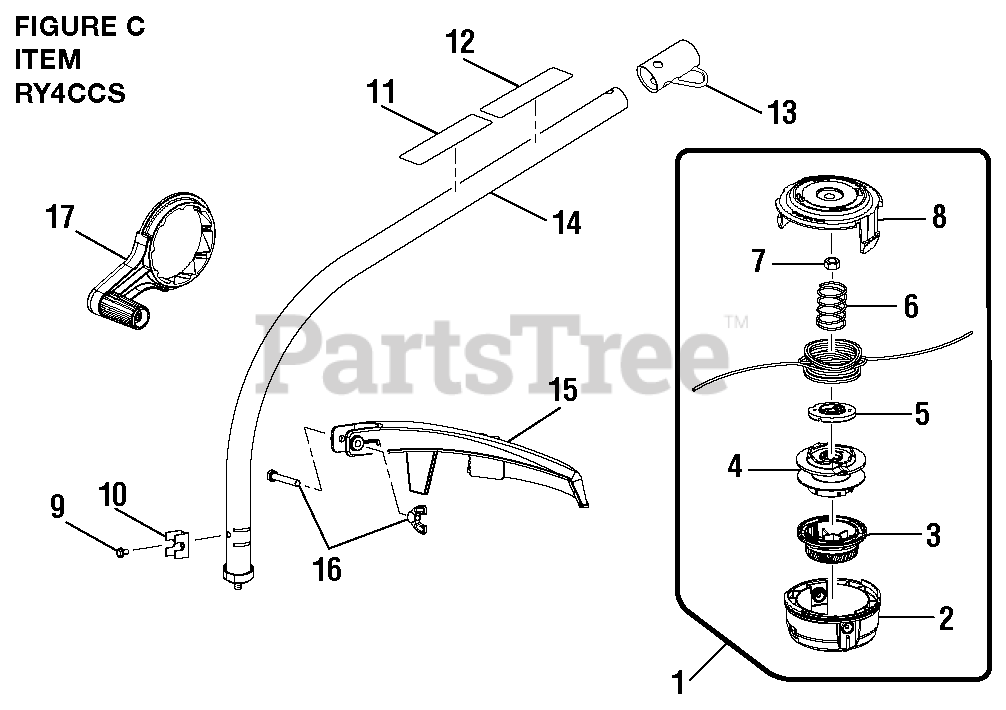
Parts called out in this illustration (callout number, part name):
1	Trimmer Head Assembly (.095)
2	Lower Housing
3	Bump Knob (Green)
5	String Guide
6	Compression Spring
7	Hex Nut (M8)
8	Upper Housing
9	Screw (#10-32 x 3/8 in., Hex Washer Hd. S.T.)
11	Expand-it Label
12	Warning Icon Label
13	Storage Hanger Cap
14	Curved Shaft Assembly
15	Grass Deflector Assembly
16	Fastener Kit
17	Crank Handle Assembly
